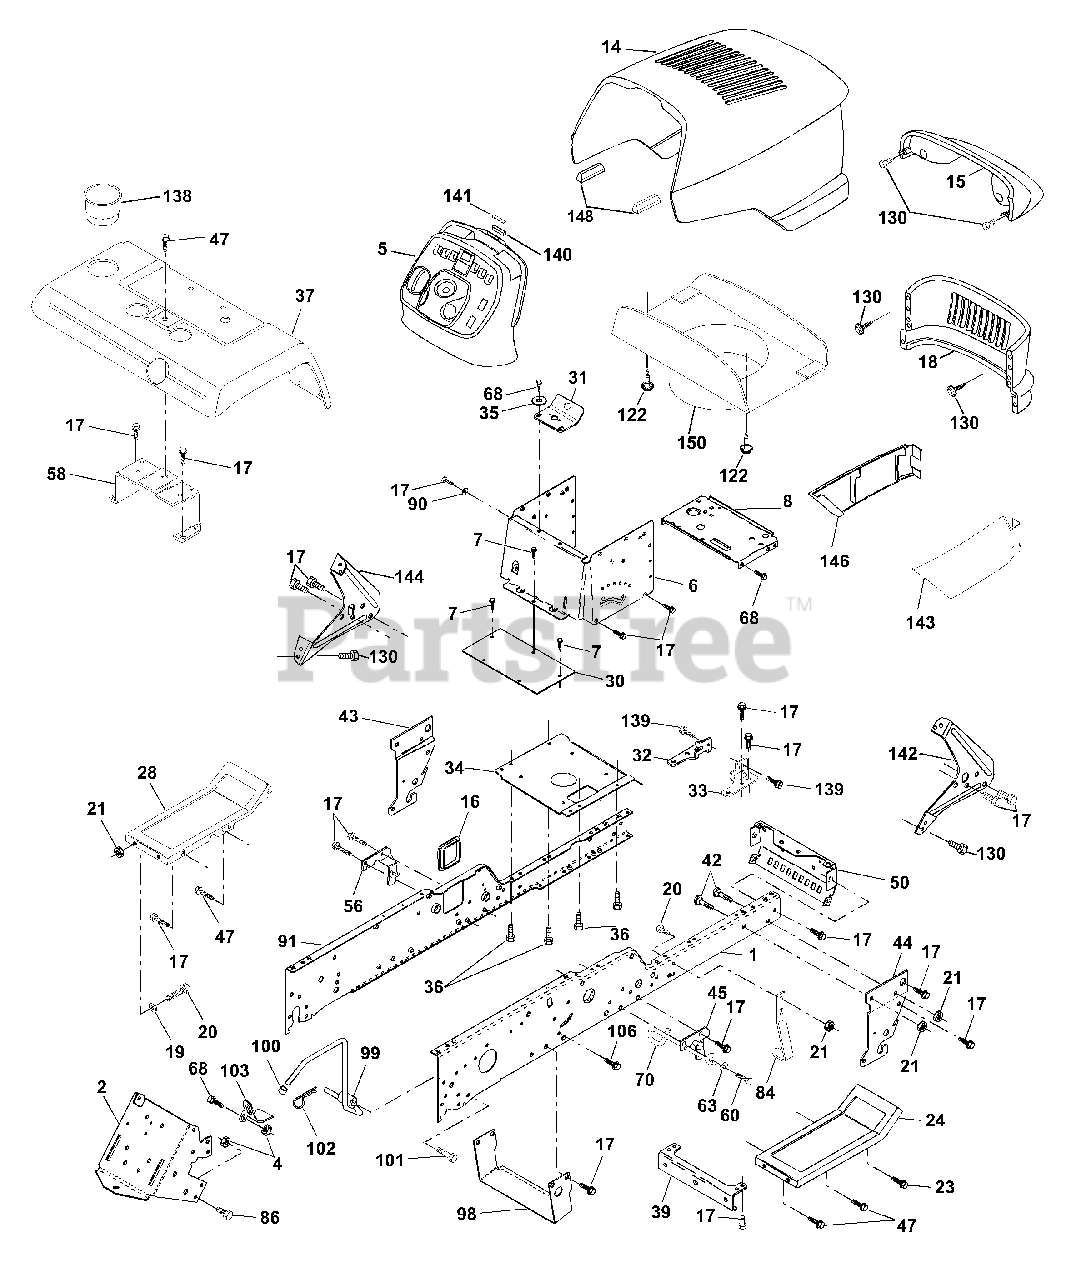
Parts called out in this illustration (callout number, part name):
1	Rail, Frame RH
2	Drawbar, Gt
4	Nut, Crownlock 7/16-14Unc
5	Dash
6	Dash Asm., Lower
7	Screw, Thd Cut 1/4-20 x 1/2
8	Support, Battery
14	Hood Asm., Pnt
15	Lens, Asm Headlight bar
16	Cover, Access
17	Screw, 3/8-16 x 3/4
18	Grille
19	Washer 13/32 x 13/16 x 12 Ga.
20	Bolt, Fin Hex 3/8-16 x 1
21	Nut, Crownlock 3/8-16 Unc
23	Screw 3/8-16 x 1
24	Footrest, RH
28	Footrest, LH
30	Saddle, Hydro 1995
31	Bracket, Supt 1-pc VGT Steering
32	Bracket, Pivot Chassis LH
33	Bracket, Pivot Chassis RH
34	Plate Asm. Engine Chassis
35	Washer 11/32 x 11/16 x 16 Ga.
36	Screw 5/16-18 x 3/4
39	Bracket, Axle Front
42	Bolt, Carriage 3/8-16 x 1
43	Bracket, Spnsn Front Lh
44	Bracket, Spnsn Front Rh
45	Bracket Asm., Susp Chassis Rh
47	Screw Thdrol 3/8-16 x 1/2 TYT
50	Bracket, Chassis Front
52	Nut, Crownlock 5/16-18
56	Bracket Asm., Susp Chassis Lh
58	Bracket Asm., Fender
60	Screw Thdrol 3/8-16 x 1-1/4
63	Washer 13/32 x 1 x 14 Ga.
68	Screw, Thd 5/16-18 x 1/2
70	Guide, Belt Mid Span
84	Stop, Over Center Mower
86	Bolt, Fin Hex 7/16-14 Unc x 1
90	Washer, Lock External Tooth 3/8
91	Rail, Frame Lh
98	Bracket Skid Chassis
99	Rod By Pass
100	Cap Parking Brake Rod
101	Screw Thdrol 3/8-16 x 1-3/4
102	Retainer, Spring
103	Lock, By Pass
106	Bolt 5/16-18 Type TT
122	Screw Hex Wshd 8-18 x 7/8
130	Screw HWHD Hi-Lo #13-16 x 3/4
138	Cupholder YTGT
139	Bolt Shoulder 5/16-18 TT
140	Magnet YTGT
141	Stricker Plate YTGT
142	Bracket Dash RH
143	Skirt Grill RH
144	Bracket Dash LH
146	Skirt Grill LH
147	Fastener Nutpal
148	Extrusion Bumper
150	Duct Heat Hood
